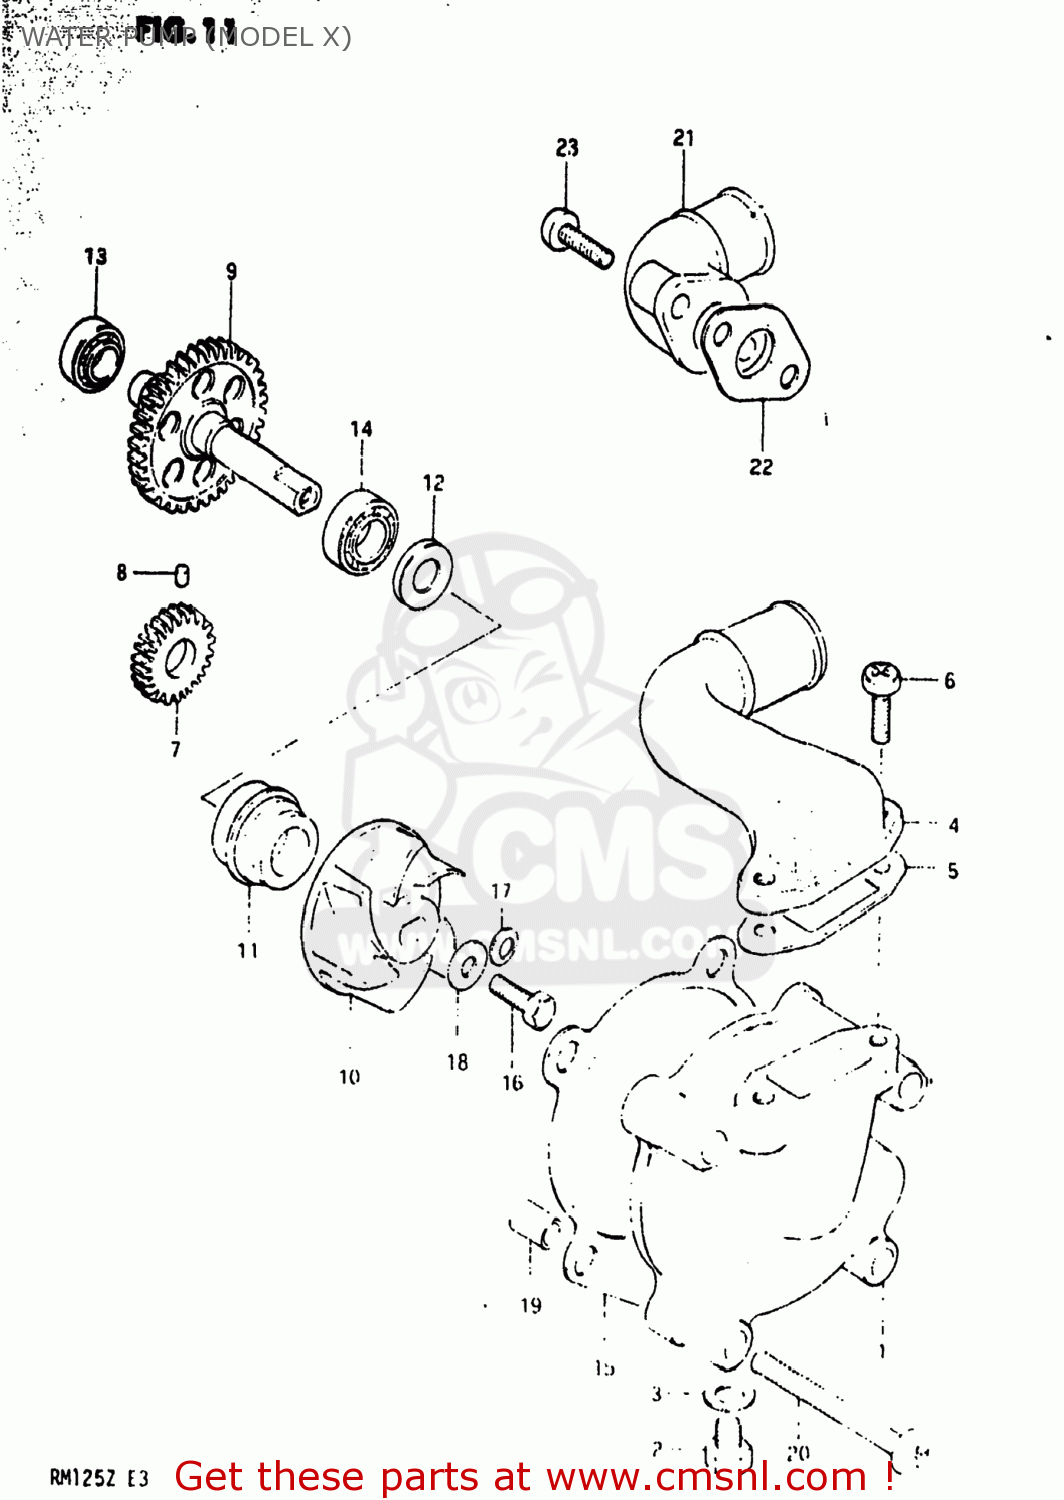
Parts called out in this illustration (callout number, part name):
1	CASE,WATER PUMP
2	BOLT 8X12
3	GASKET,DRAIN (NAS)
4	CONNECTOR
5	GASKET,WATER PUMP INLET (MCA)
6	SCREW
7	GEAR,WATER PUMP DRIVE
8	PIN 3X5
9	SHAFT,WATER PUMP
10	IMPELLER,WATER PUMP
11	SEAL,WATER PUMP SHAFT
12	SEAL,OIL(10X21X5)
13	BEARING(10X22X6)
14	BEARING
15	GASKET,WATER PUMP CASE (MCA)
16	BOLT(6X13)
17	WASHER
18	GASKET (NAS)
19	PIN
20	SCREW (6X45)
21	O-RING,WATER PUMP CASE
22	GASKET,WATER PUMP OUTLET (MCA)
23	SCREW
